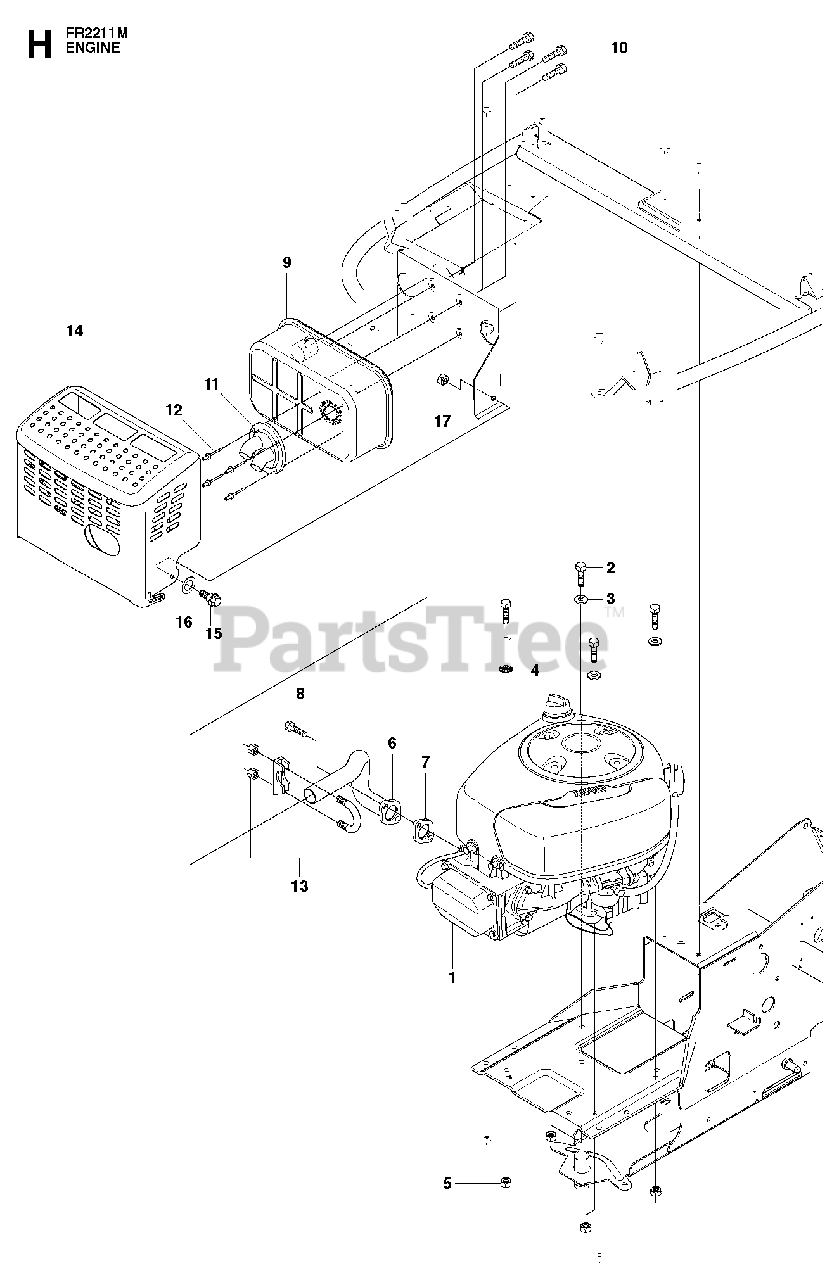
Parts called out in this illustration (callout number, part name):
3	WASHER BRB 8.4X17
5	LOCKNUT M8
9	MUFFLER
16	SPRINGWASHER
17	LOCKNUT M8
